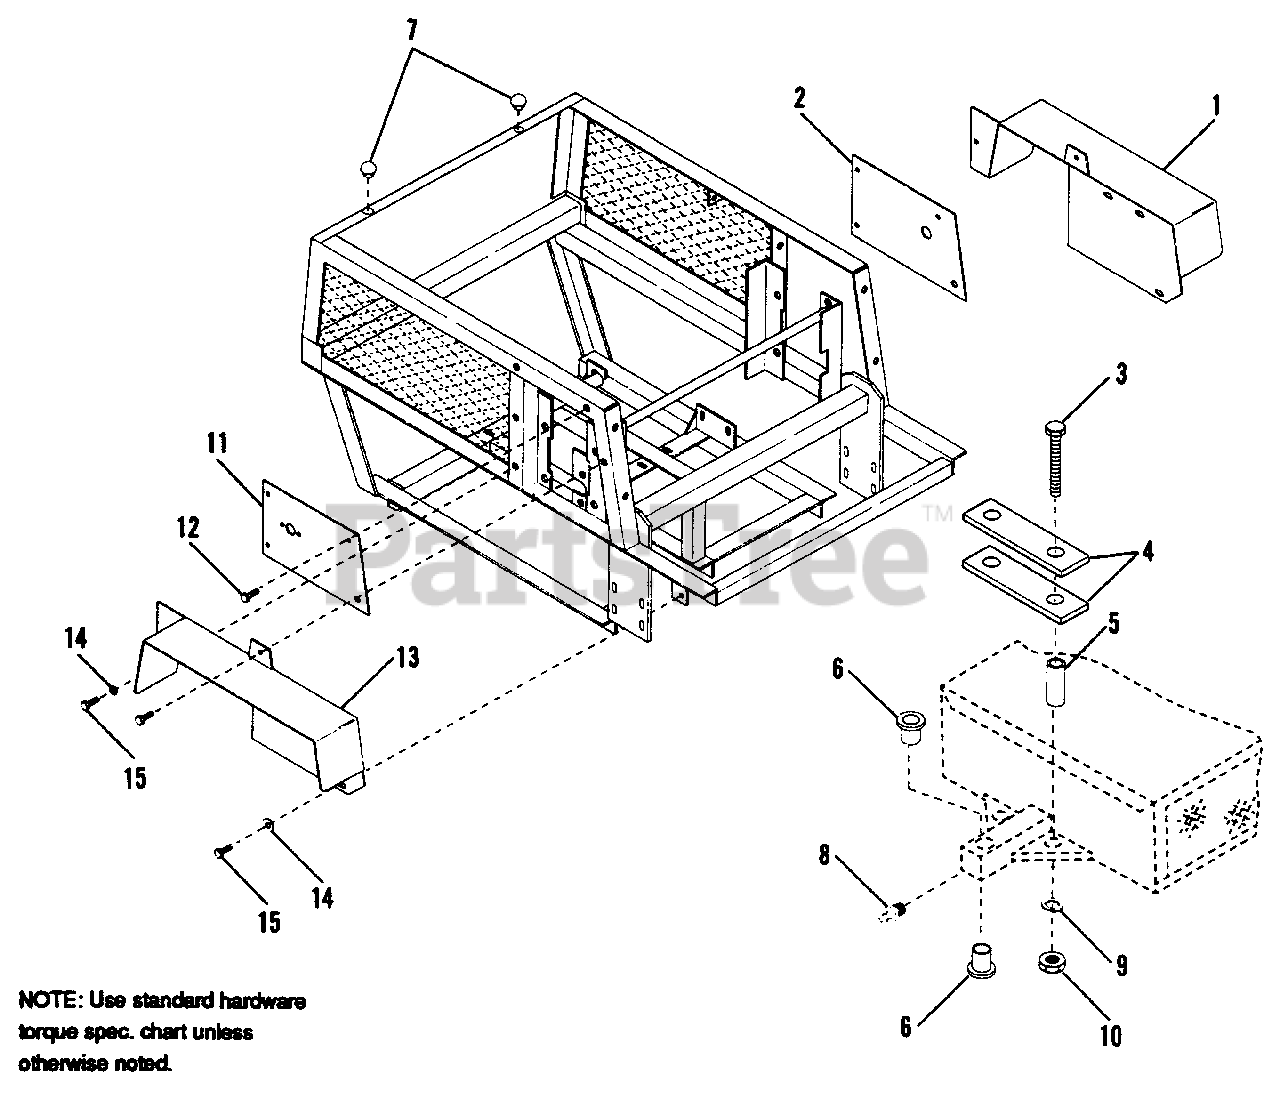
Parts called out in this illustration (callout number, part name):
1	FENDER ASSY., Left Hand
2	SIDE, Left Hand
3	CAPSCREW, Hex 7/16-14 x 4
4	PLATE, Weight
5	TUBE, Spacer
6	BUSHING, Flanged
7	BUMPER, Rubber
8	FITTING, Grease
9	LOCKWASHER, Spring 5/16
10	NUT, Hex 7/16-14
11	SIDE, Right Hand
12	SCREW, Taptite 1/4-20 x 5/8
13	FENDER ASSY., Right Hand
14	WASHER, Plain
15	CAPSCREW, Hex 5/16-18 x 3/4
